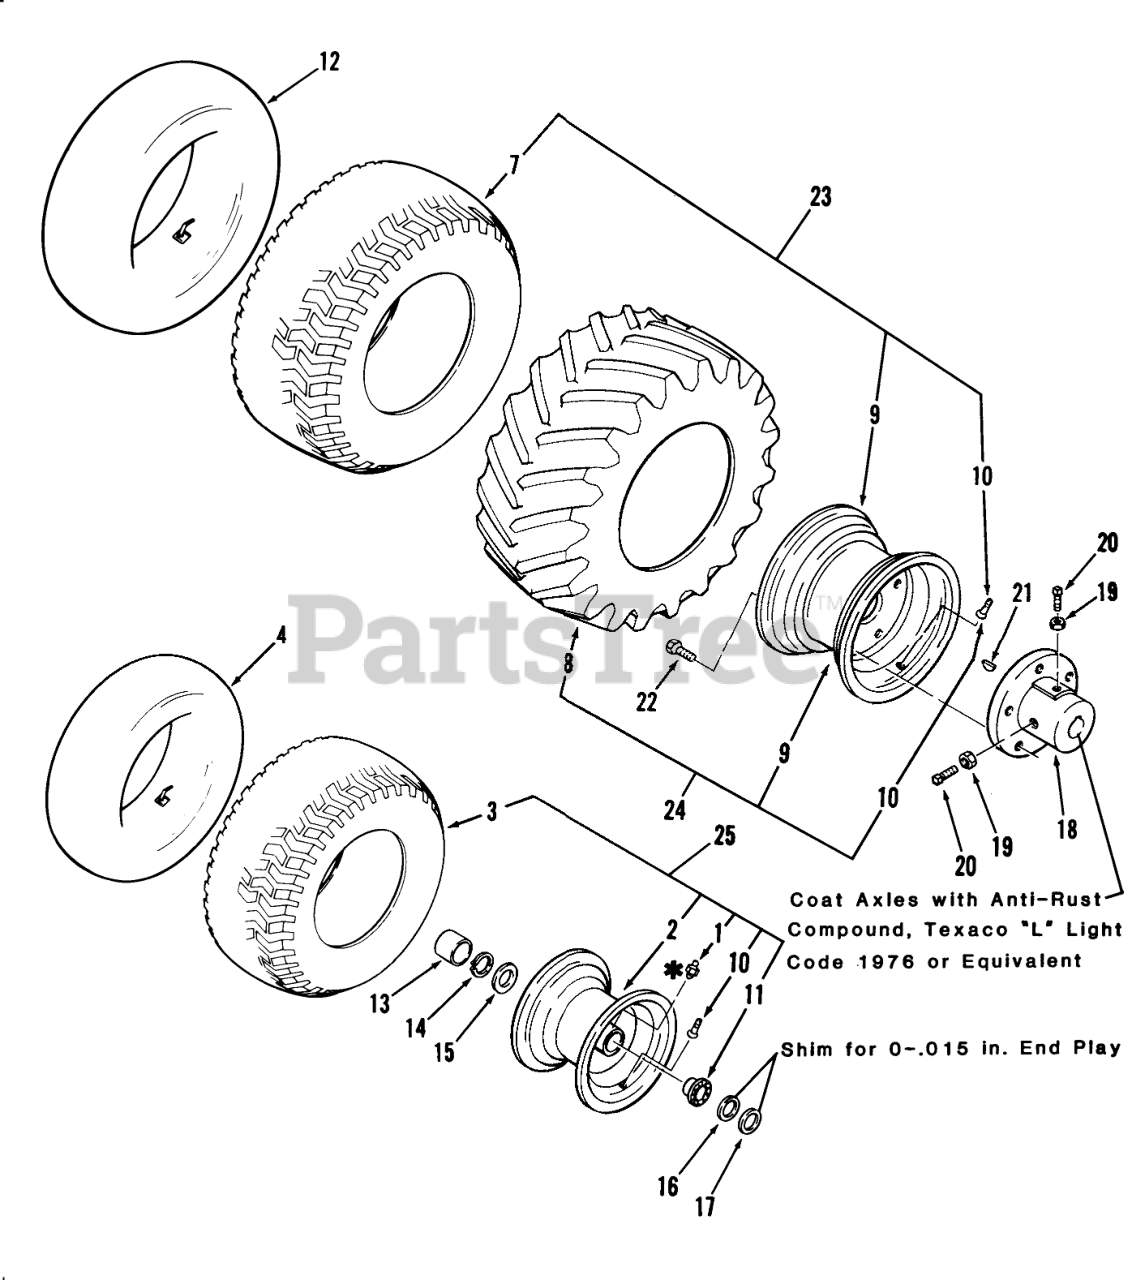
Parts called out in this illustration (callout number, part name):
1	Zerk
2	Front Wheel (Includes Item 1)
3	TIRE TURF SAVER 16X6.50-8
4	TUBE-INNER
7	TIRE 9.50 X 12
7	Tire
8	Tire-Cleat, Rear
9	Wheel
10	VALVE
11	Ball Bearing
12	TUBE-INNER
13	HUB CAP
13	HUB CAP-FLAT BLACK
14	Snap Ring
15	WASHER-WHEEL
16	WASHER
17	WASHER-SHIM
18	Hub Rear
19	Nut
20	Screw-Set
21	KEY-WOODRUFF
22	Lug Nut
23	Engine
23	Wheel and Tire
24	Right Rear Wheel and Tire Assy-Cleat
24	Left Rear Wheel and Tire Assy-Cleat
25	ASSY-WHEEL & TIRE
